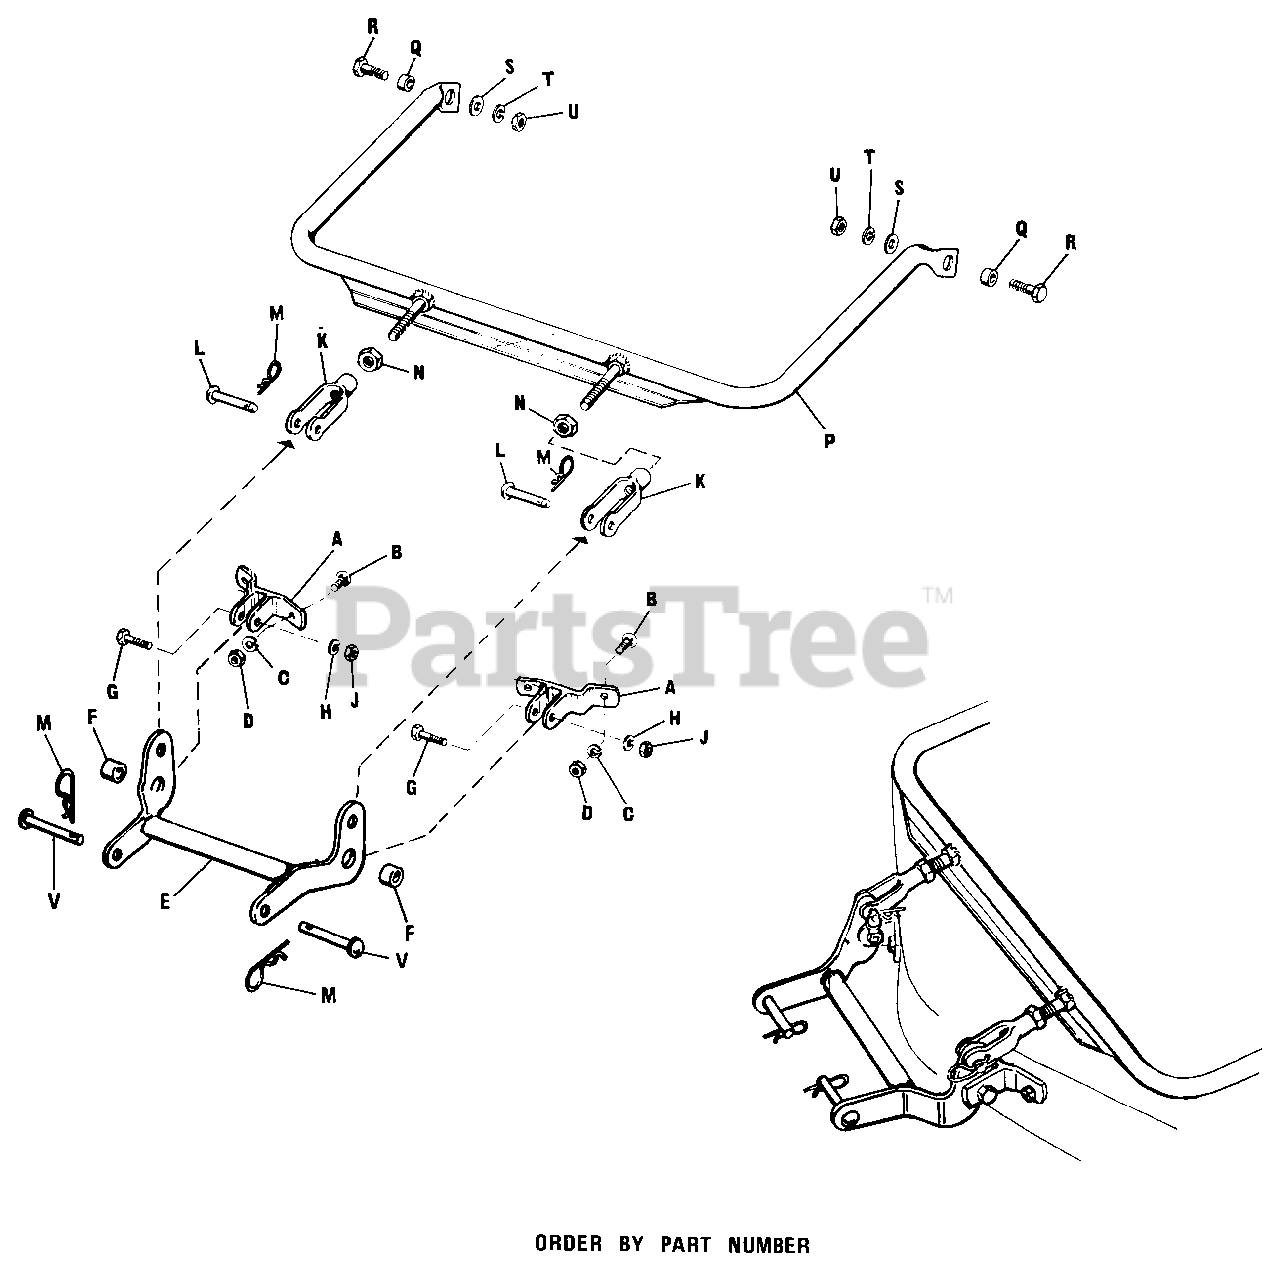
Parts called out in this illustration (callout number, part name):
A	Front Bracket Assembly
B	Carriage Bolt, 3/8"-16 x 1"
C	Lock Washer, 3/8"
D	Full Hex. Nut, 3/8"-16
E	Rocker Arm
G	Hex. Cap Screw, 1/2"-13 x 1-1/4"
H	Lock Washer, 1/2"
J	Full Hex Nut, 1/2"-13
K	End Adj. Yoke
M	Spring Clip
N	Hex. Jam Nut, 1/2"-20
P	Bail Assembly
R	Hex. Cap Screw, 1/2"-13 x 1-1/4"
S	Plain Washer, 1/2"
T	Lock Washer, 1/2"
U	Full Hex Nut, 1/2"-13
V	Pin
